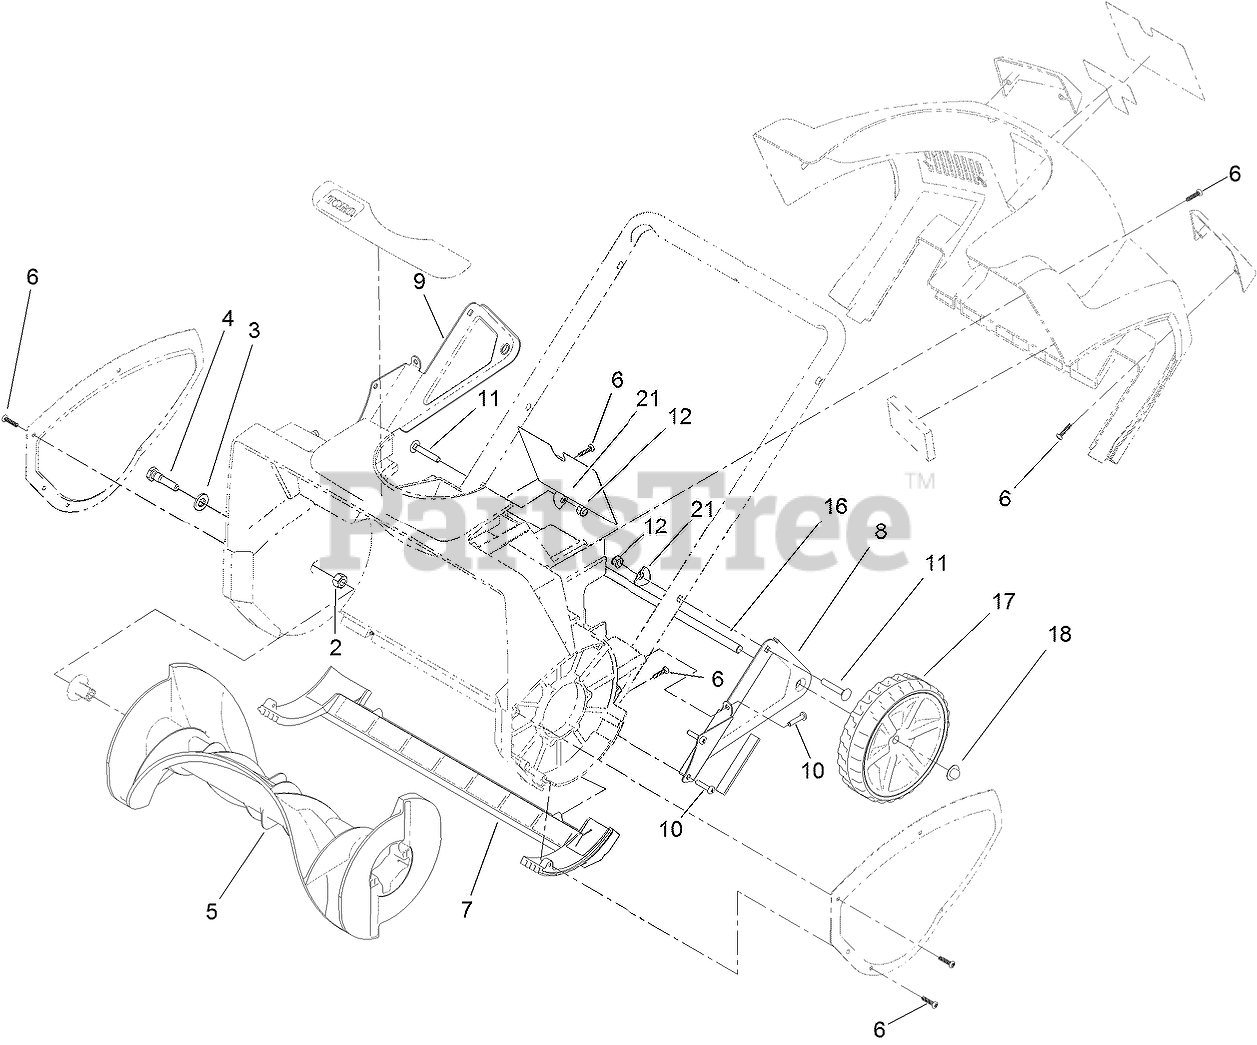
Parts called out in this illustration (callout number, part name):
2	NUT-LOCK
3	WASHER-PLAIN
4	PIN-ROTOR
5	ROTOR ASM
6	SCREW-PPH
7	SCRAPER
8	BRACKET-WHEEL, LH
9	BRACKET-WHEEL, RH
10	SCREW-PPH
11	SCREW-CARR
12	NUT-LOCK, NI
16	AXLE-WHEEL
17	WHEEL ASM
18	NUT-PUSH
21	WASHER
